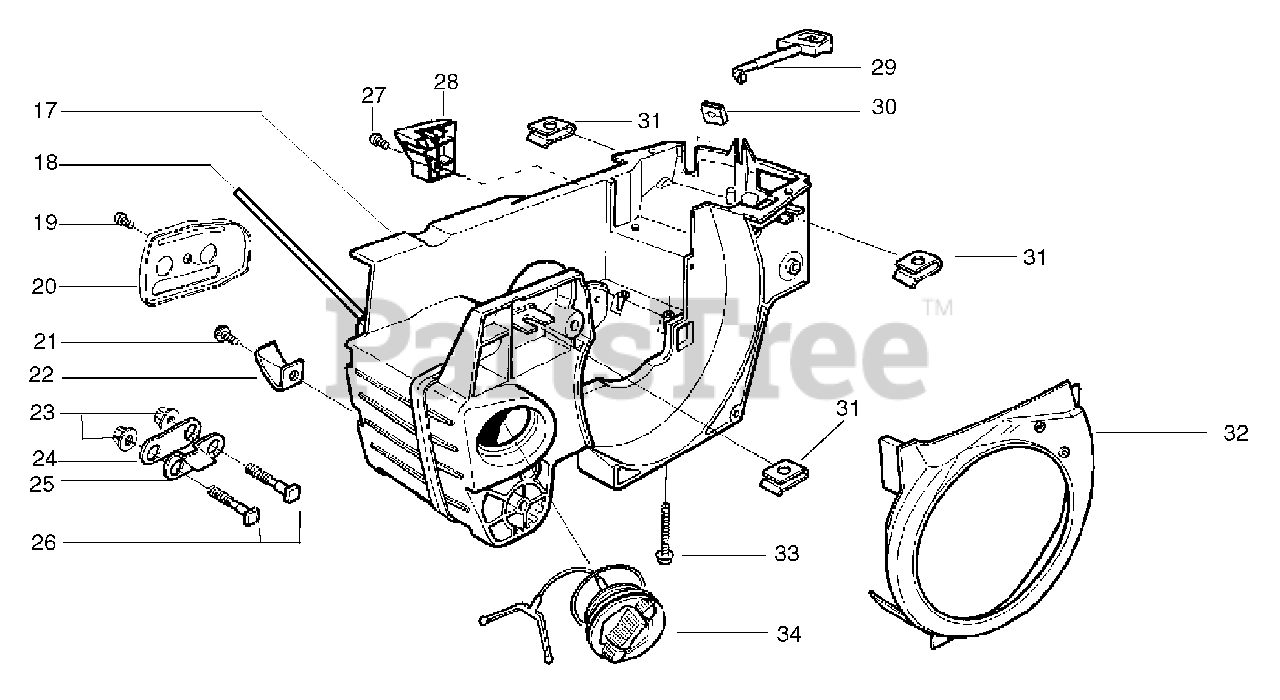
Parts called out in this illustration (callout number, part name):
17	Kit - Chassis Ass'y.
18	Tube-Oil Vent
19	Screw
22	Chain Catcher
25	Bar Stud Plate
29	Choke Lever
31	Type "U" Speed Nut
32	Baffle Plate
34	Assy.- Oil Tank Cap
